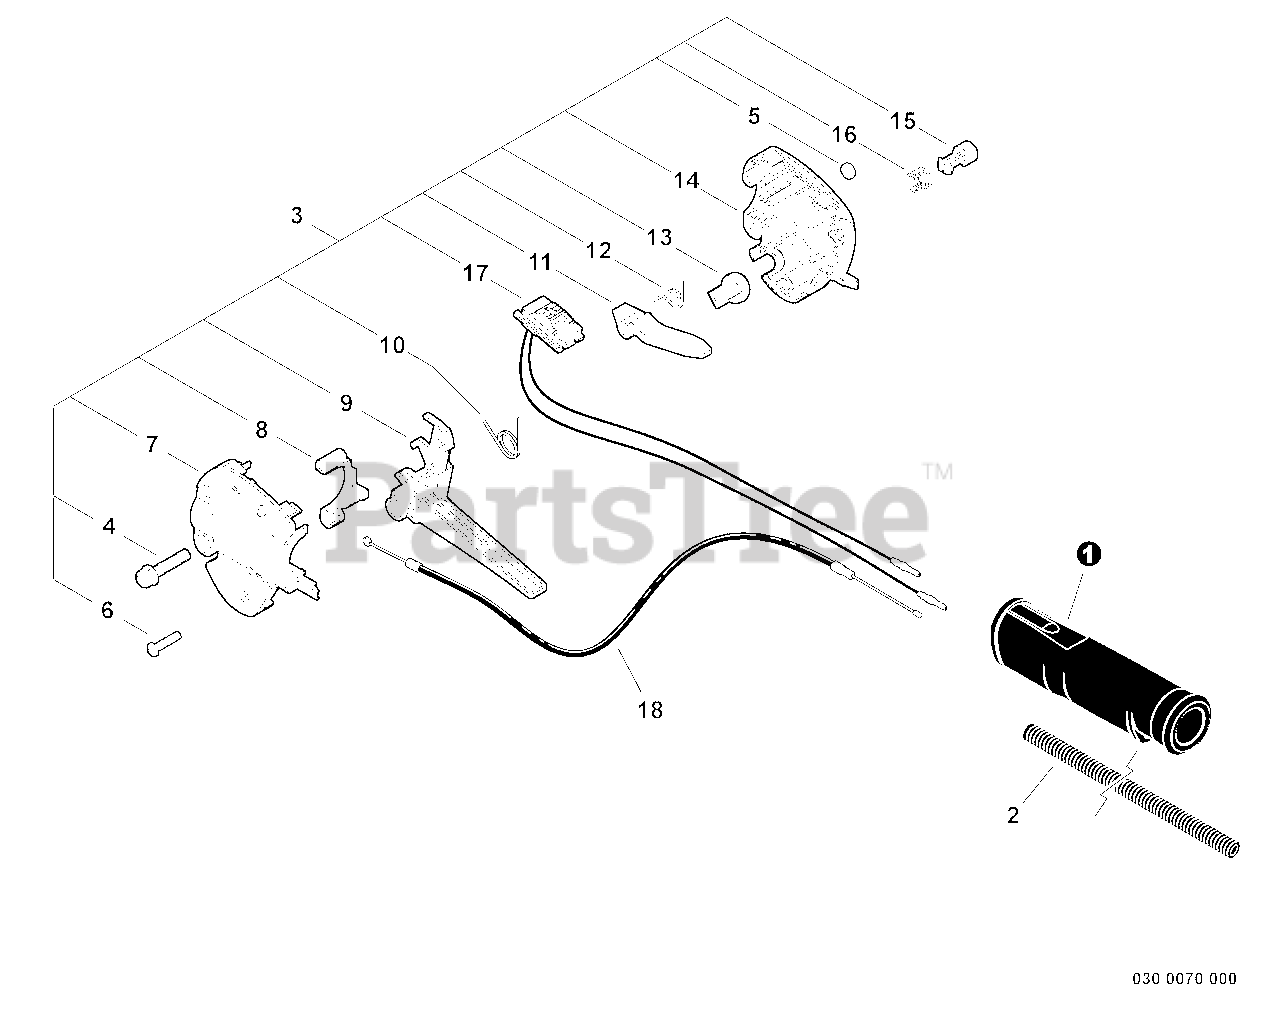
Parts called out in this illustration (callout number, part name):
1	GRIP - REAR
2	TUBE, PROTECTIVE - CORRUGATED
3	CONTROL HANDLE KIT
4	SCREW - 5X20
5	NUT - 5
6	SCREW - 4X16 -- TAPPING
7	HANDLE, CONTROL - LEFT
8	LOCKOUT, THROTTLE
9	TRIGGER, THROTTLE
10	SPRING, TRIGGER
11	LEVER, TRIGGER LOCKOUT
12	SPRING, LOCKOUT LEVER
14	HANDLE, CONTROL - RIGHT
15	LOCK, THROTTLE
17	SWITCH, IGNITION
18	CABLE, THROTTLE
